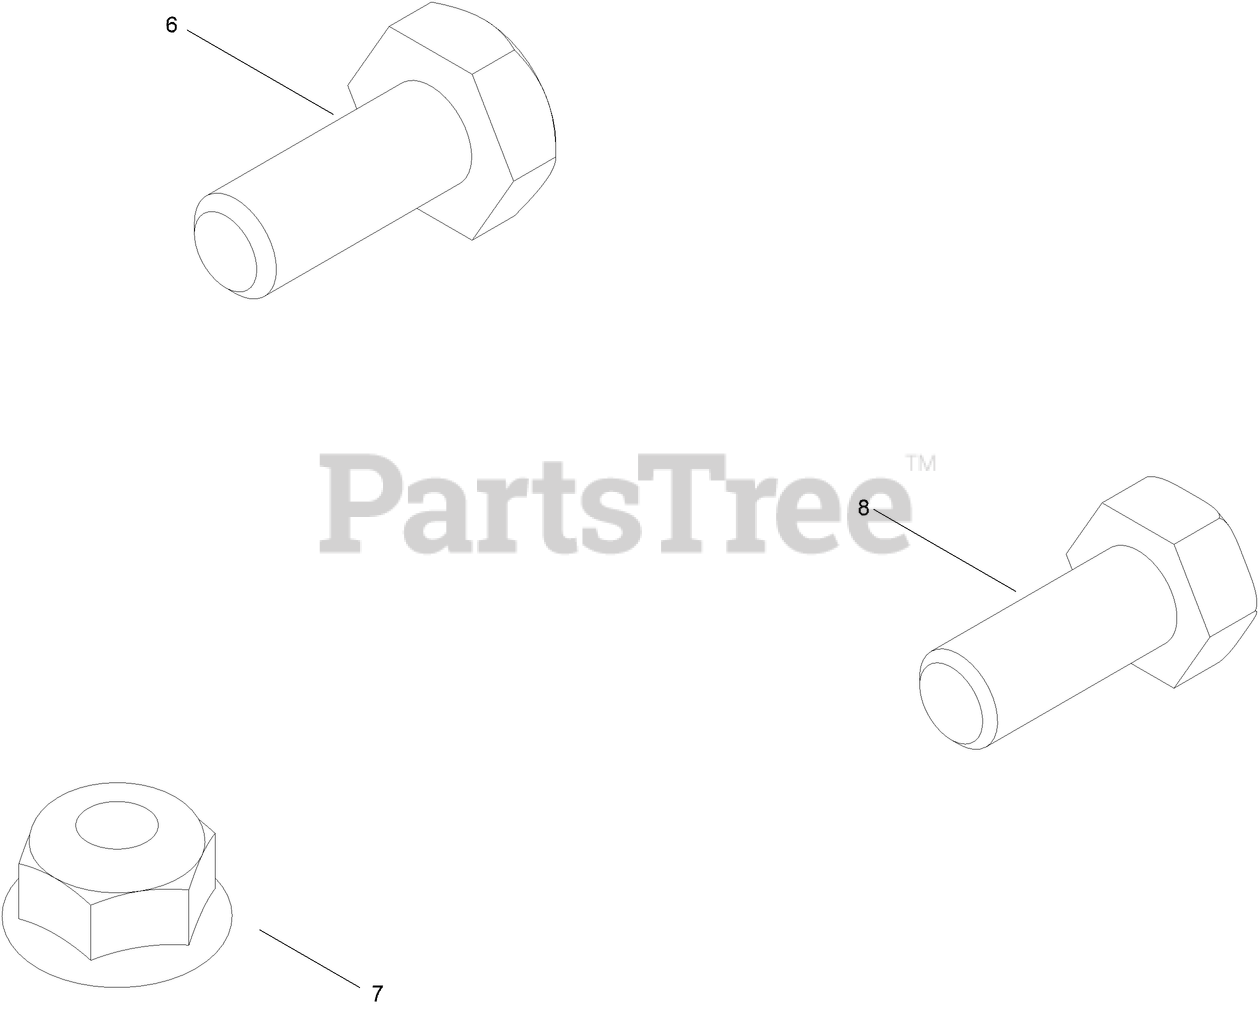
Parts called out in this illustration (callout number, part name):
6	SCREW-HH
7	NUT-FLANGE, NI
8	SCREW-HH
